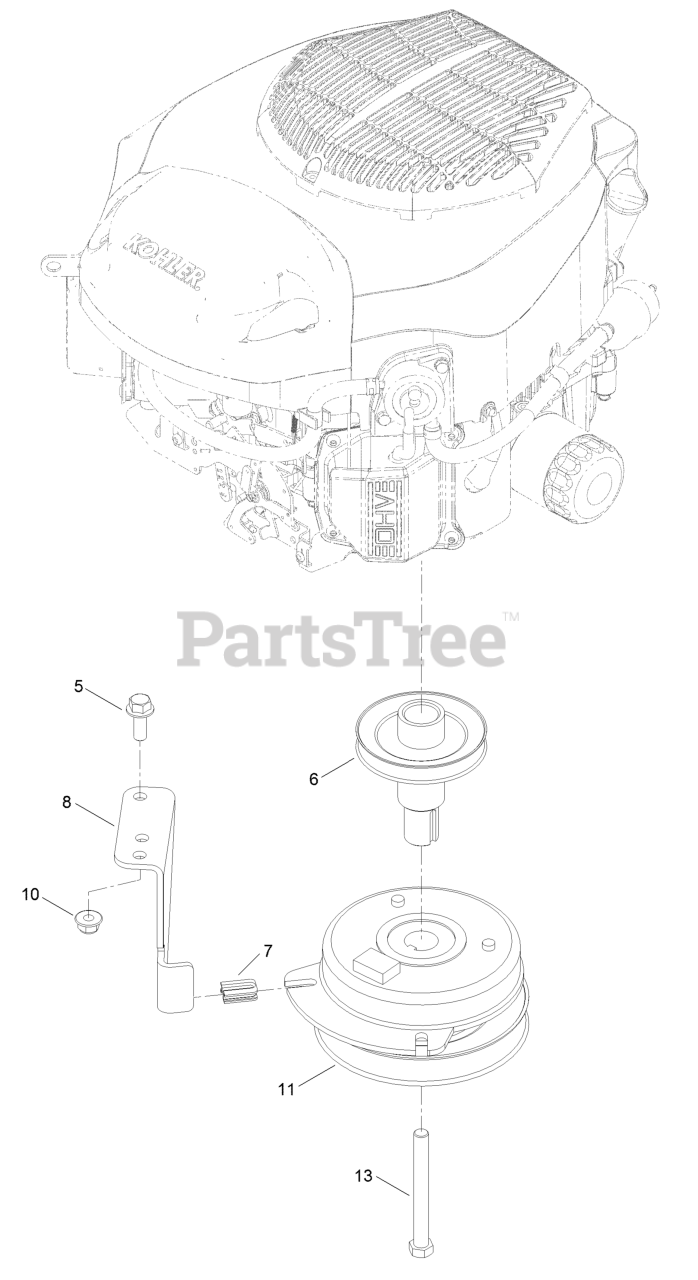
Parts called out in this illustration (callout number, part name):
5	SCREW-HHF 3/8-16 X 1
6	PULLEY-ENGINE
7	ISOLATOR-CLUTCH
8	STOP-CLUTCH
10	NUT-HF, NI
11	CLUTCH-PTO
13	SCREW-HH
